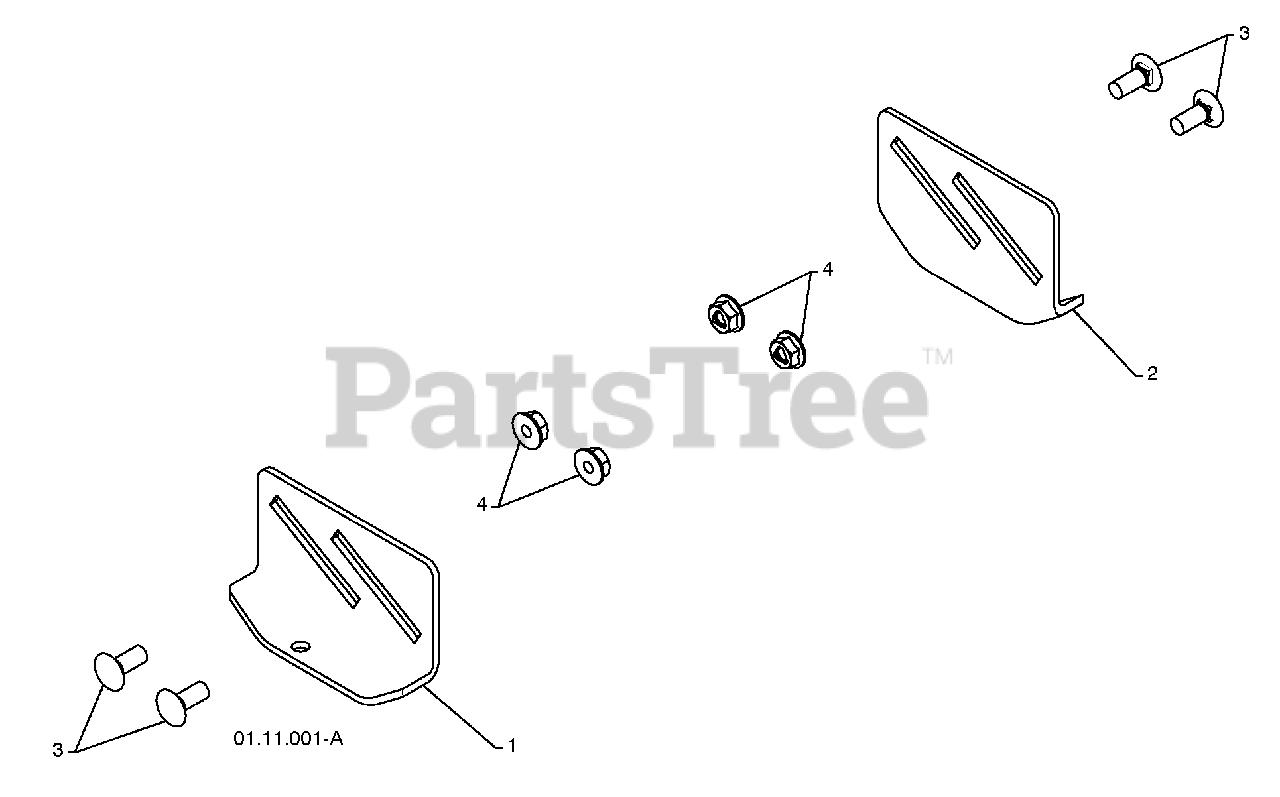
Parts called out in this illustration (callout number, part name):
1	SKID PLATE LH
2	SKID PLATE RH
3	CARRIAGE BOLT 5/16-18 X .75
4	NUT 5/16-18
